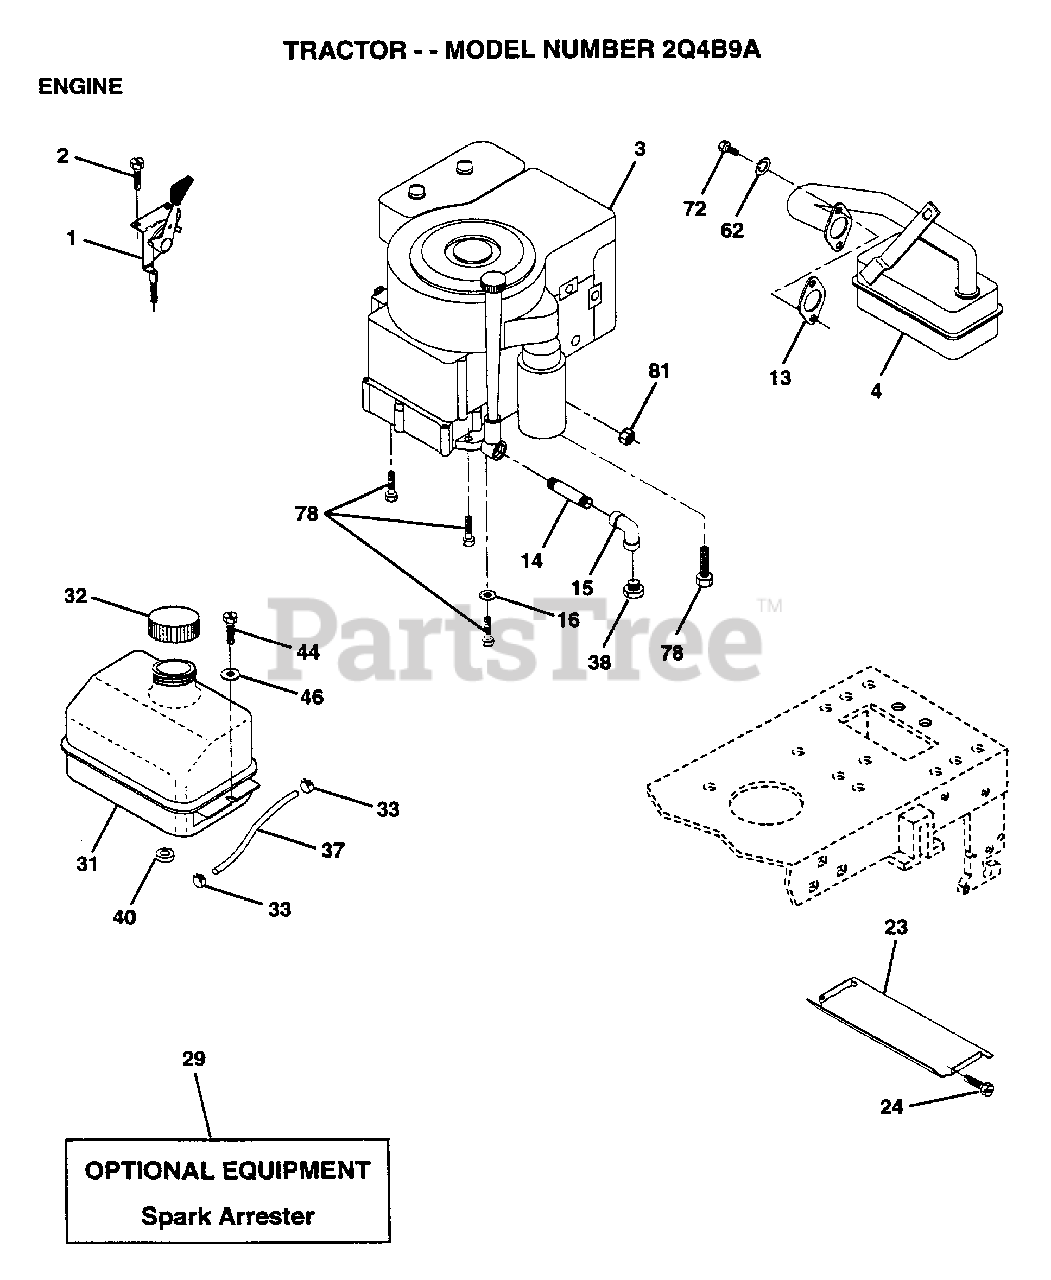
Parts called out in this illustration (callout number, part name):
1	THROTTLE CONTROL
2	SCREW LT
4	MUFFLER
14	PIPE NIPPLE
15	ELBOW
16	LOCKWASHER
23	HEAT SHIELD
24	SCREW
31	TANK.FUEL.LT.
32	CAP ASM FUEL
33	HOSE CLAMP
37	LINE FUEL
44	SCREW HEX CRT
46	WASHER
62	LOCKWASHER
72	SCREW
78	SCREW
81	NUT
